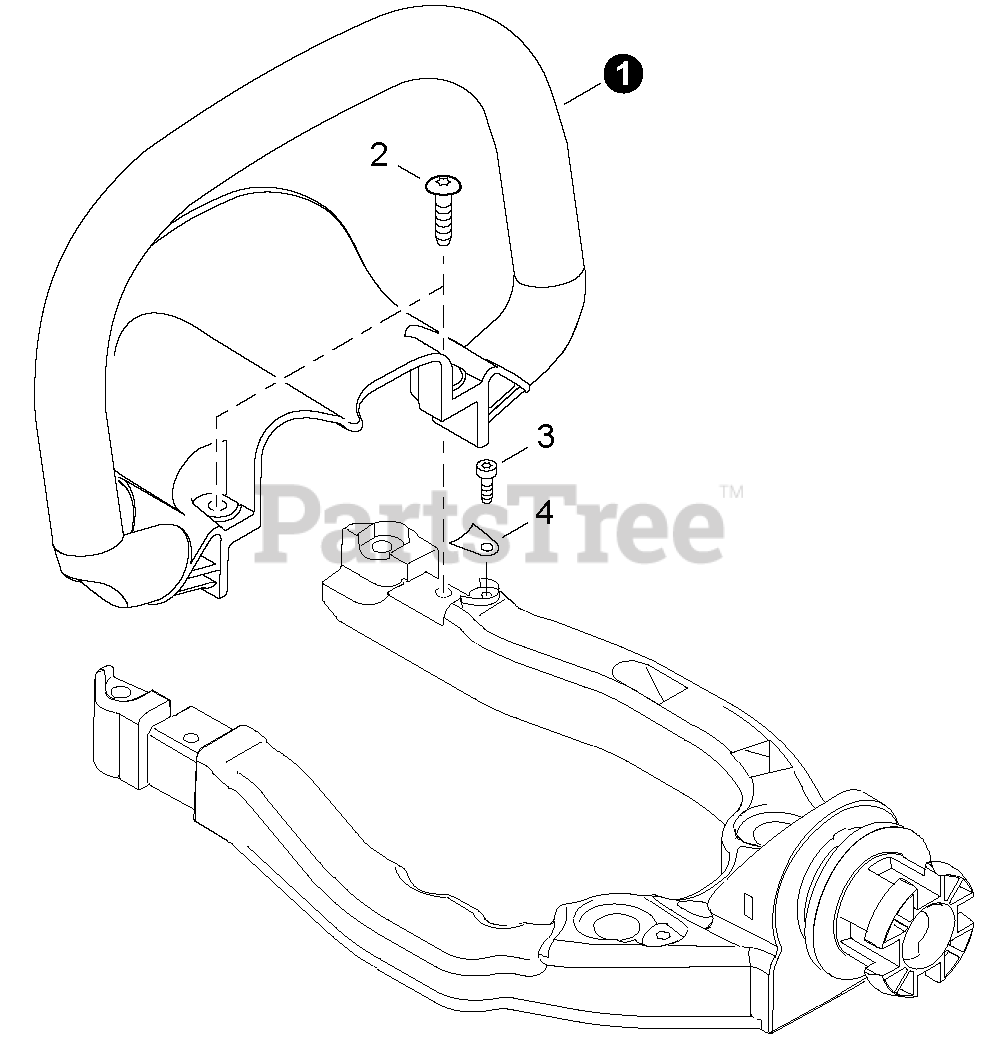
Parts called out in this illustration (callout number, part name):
1	HANDLE - FRONT
2	SCREW - 6
3	SCREW - 4X12
4	RETAINER, BRAKE BAND
